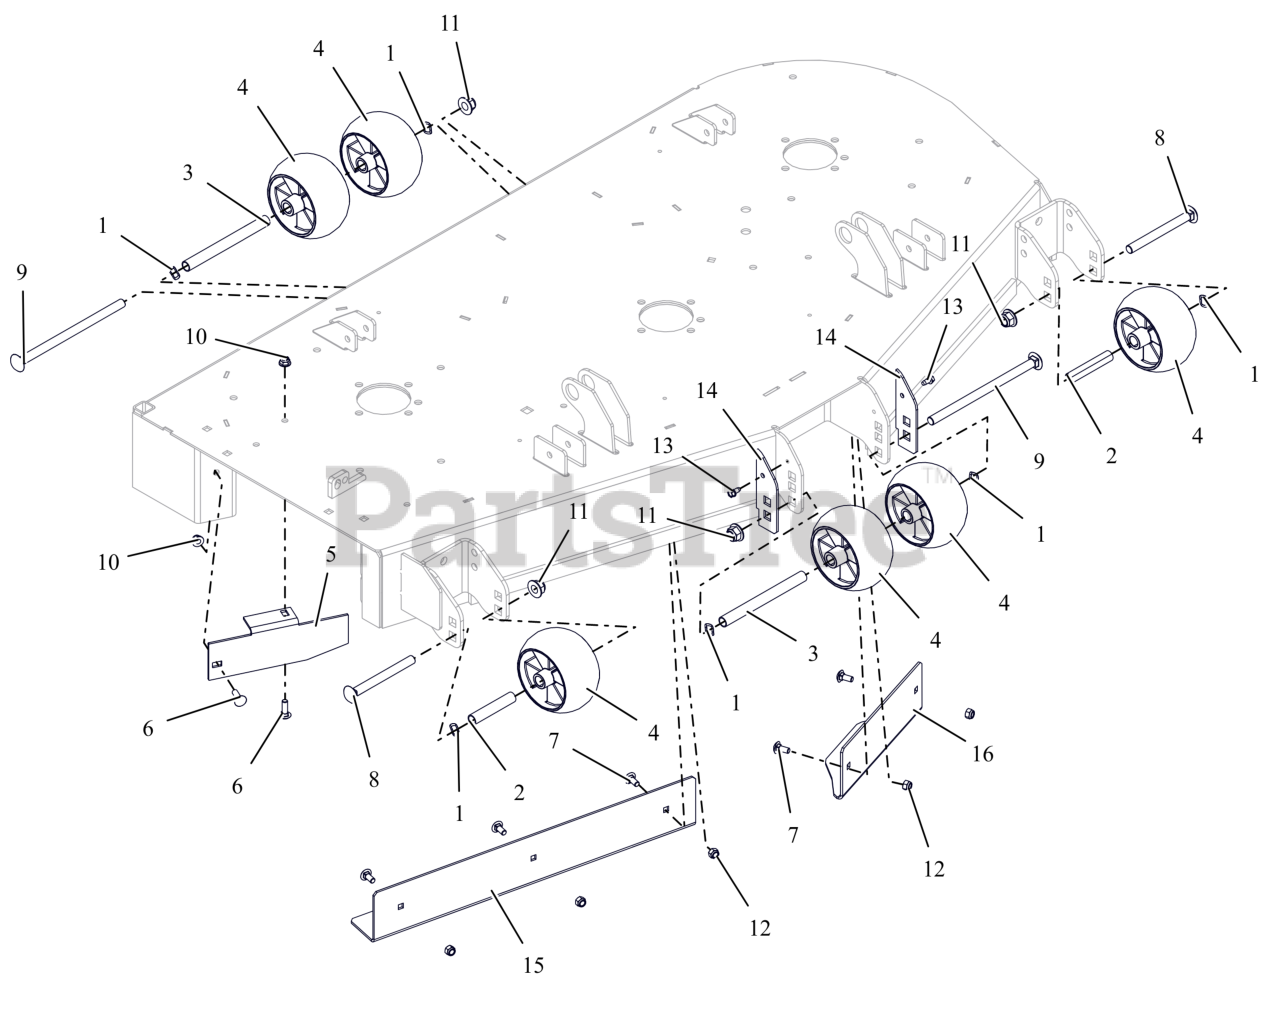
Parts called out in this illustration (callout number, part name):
1	WAVE WASHER .531X.781X.125FH
2	SPACER, .510X.625X3.35
3	SPACER, .510X.625X6.50
4	ANTI-SCALP WHEEL - 5X3 CTR
5	BAFFLE, DISCHARGE, 52"
6	BLT,RHSN .31-18X1.00 G5 ZCC
7	BLT,RHSN .31-18X.75 G5 ZCC
8	BLT, RHSN .50-13X5.00 G5 ZCC
9	BLT, RHSN .50-13X8.50 G5 ZCC
10	NUT,LK-NYL-FLG .31-18 G5ZC120
11	NUT,NYL-FLG .50-13 GF ZCC
12	NUT,NYL .31-18 G5 ZCC
13	SCR-TAP .25-20X.50 HWH ZCC
14	PLATE, ANTI SCALP WHEEL PLATE CE (ORANGE)
15	BAFFLE, 52" RH VACUUM (ORANGE)
16	BAFFLE, 52" LH VACUUM
